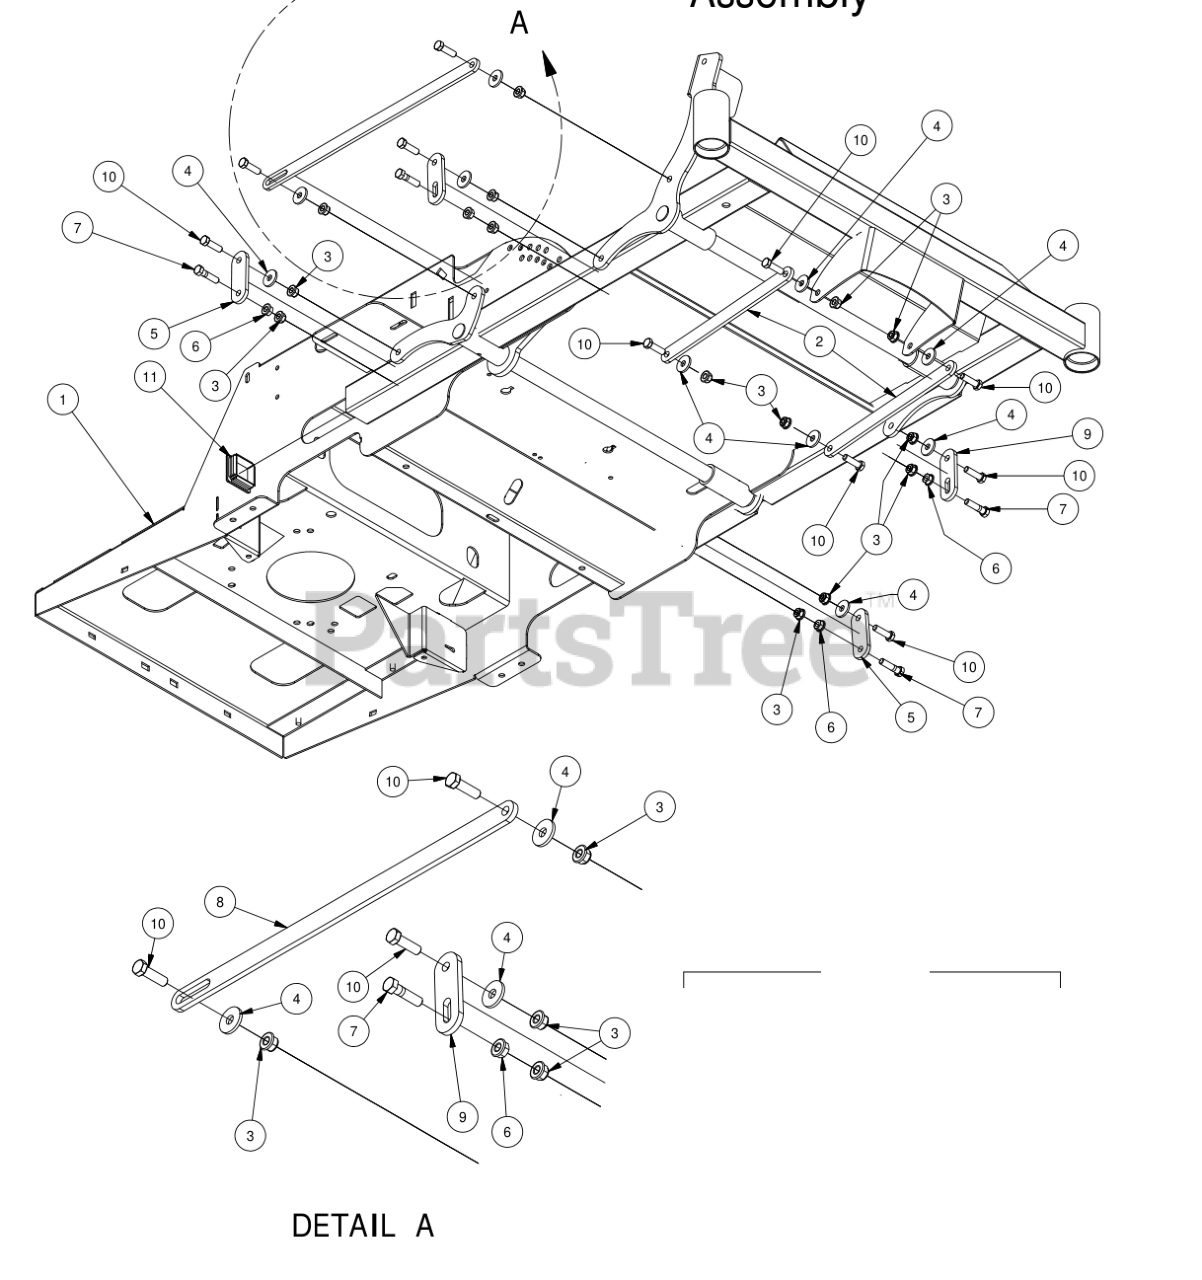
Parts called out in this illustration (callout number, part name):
1	2014 54" MZ Magnum Frame
2	MZ Front Arm
3	3/8" Nylock Flange Nut
4	.390 ID Plastic Washer
5	Deck Spacer MZ
6	3/8" Flange Nut
7	3/8" x 1 1/2" Hex Bolt
8	MZ Deck Linkage Rod
9	Deck Spacer MZ (Front)
10	3/8" x 1 1/4" Hex Bolt
11	2x2 Square Plug
